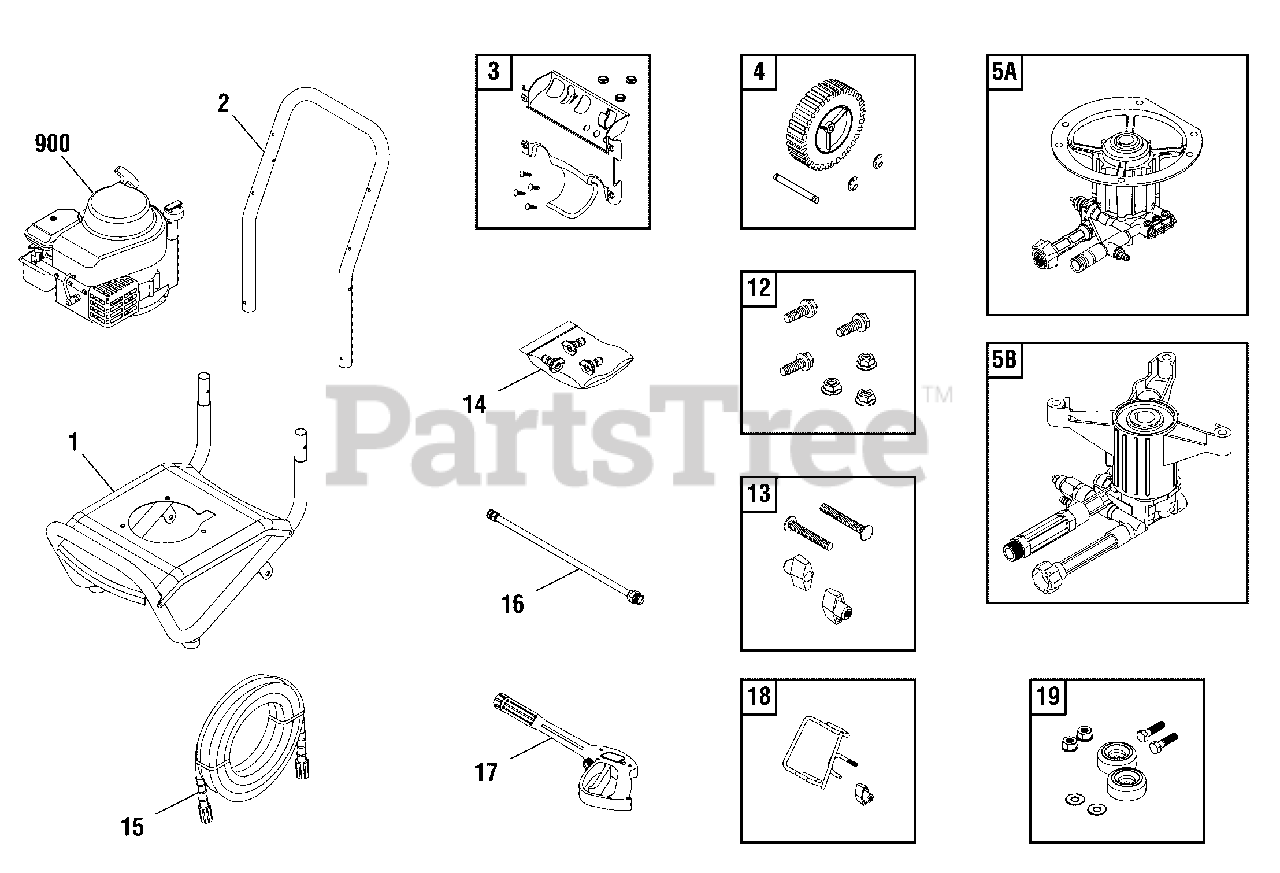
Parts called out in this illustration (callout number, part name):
2	Handle
3	Kit, Billboard w/Decals & Clips
5A	Assy, Pump
12	Kit, Pump Mounting Hardware
13	Kit, Handle Connector
15	Hose
16	Extension
17	Gun
18	Kit, Gun Holder
19	Kit, Vibration Mount
900	* Engine
